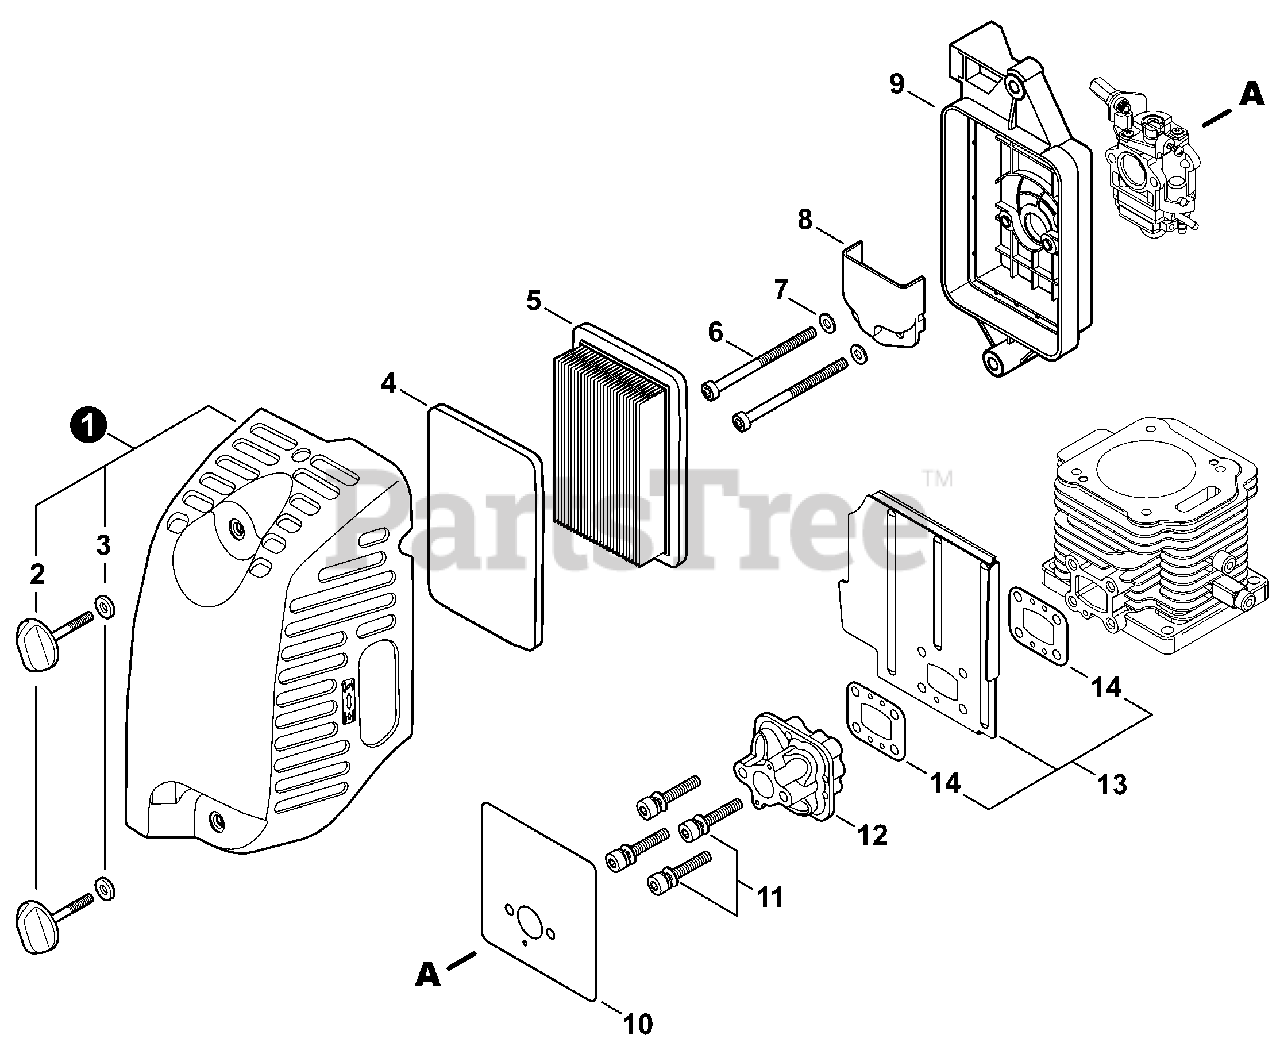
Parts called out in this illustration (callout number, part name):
1	COVER ASSY, AIR FILTER
2	THUMBSCREW
3	WASHER 5
4	PRE-FILTER, FOAM
5	FILTER, AIR
6	BOLT SS M5×70
7	WASHER 5.5×12×0.8
8	PLATE, DEFLECTOR
9	CASE ASSY, AIR FILTER
10	GASKET, CARBURETOR
11	BOLT SS M5×30
12	INSULATOR, INTAKE
13	SHIELD ASSY, INTAKE HEAT
14	GASKET, INTAKE
